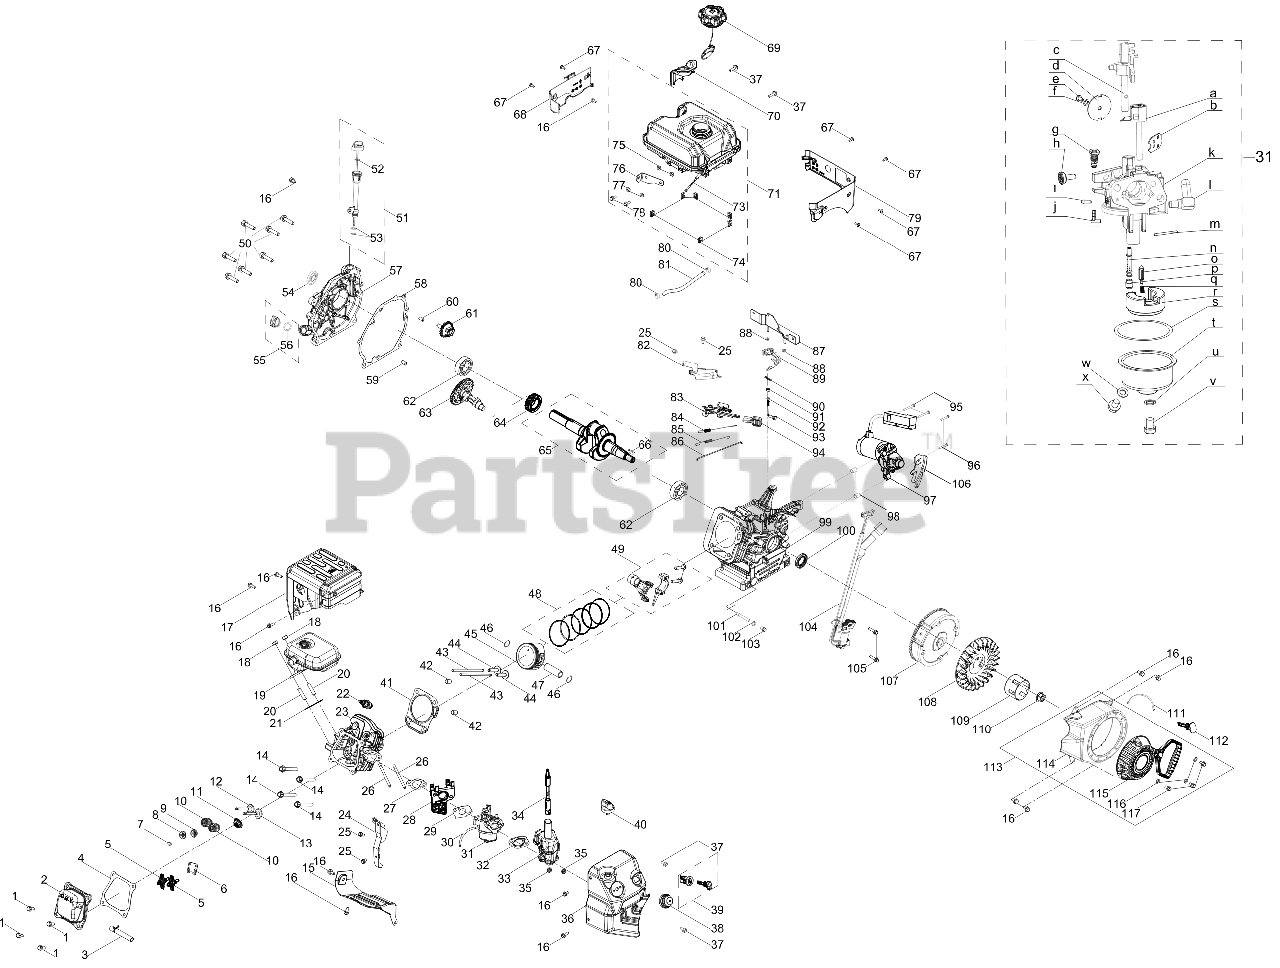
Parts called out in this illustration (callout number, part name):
1	BOLT M6 x 16
2	VALVE COVER
3	BREATHER HOSE
4	VALVE COVER GASKET
5	ROCKER ARM ASSEMBLY
6	ROCKER ARM BASE
7	EXHAUST VALVE ADJUSTER
8	EXHAUST VALVE SPRING RETAINER
9	INTAKE VALVE SPRING RETAINER
10	VALVE SPRING
11	INTAKE VALVE SEAL
12	EXHAUST VALVE
13	INTAKE VALVE
14	BOLT M8-1.25 x 55 GR10.9
15	AIR SHIELD
16	BOLT M6-1 x 12 GR8.8
17	MUFFLER GUARD
20	STUD M8 x 36
21	MUFFLER GASKET
22	SPARK PLUG
23	CYLINDER HEAD
24	SNOW GUARD
25	BOLT M6-1 x 12 GR8.8
26	STUD M6 x 90
27	CARBURETOR INSULATOR GASKET
28	CARBURETOR INSULATOR
29	CARBURETOR GASKET
30	PRIMER HOSE
31	CARBURETOR ASSEMBLY
32	CARBURETOR GASKET PLATE
33	HEATER BOX
34	CHOKE LEVER
36	CONTROL PANEL
37	BOLT M6-1 x 18 GR8.8
39	ENGINE KEY SWITCH ASSEMBLY
40	CHOKE LEVER
41	CYLINDER HEAD GASKET
43	PUSH ROD
46	PISTON PIN SNAP RING
47	PISTON PIN
48	PISTON RING SET
49	CONNECTING ROD ASSEMBLY
50	BOLT M8-1.25 x 32 GR5.8
51	DIPSTICK ASSEMBLY
52	DIPSTICK O-RING
53	OIL FILL TUBE O-RING
54	OIL SEAL
56	O-RING 15.8 x 2.5
57	CRANKCASE COVER
58	CRANKCASE COVER GASKET
59	DOWEL PIN
60	DOWEL PIN
61	GOVERNOR GEAR/SHAFT ASSEMBLY
64	DRIVE TIMING GEAR
65	CRANKSHAFT
66	FLYWHEEL KEY
67	BOLT: M5 x 14
68	FUEL TANK SHROUD (RH)
70	DECORATIVE COVER
73	FUEL FILTER
74	FUEL TANK MOUNT THREADED TAB
76	FUEL TANK MOUNT TAB
77	WASHER 6.5 x 1.5 x 12
78	BOLT M6 x 20
79	DECORATIVE SHEET (LH)
80	HOSE CLAMP
81	FUEL HOSE 6.3 x 12.5 x 162
82	GOVERNOR SHIELD
83	GOVERNOR GEAR BRACKET ASSEMBLY
84	GOVERNOR SPRING
85	THROTTLE RETURN SPRING
86	GOVERNOR ROD
87	FUEL TANK BRACKET
89	GOVERNOR LEVER
90	COTTER PIN
91	GOVERNOR SEAL
93	GOVERNOR SHAFT
94	THROTTLE CONTROL KNOB
96	BOLT M6-1 x 32 GR8.8
97	ELECTRIC STARTER
98	DOWEL PIN
100	OIL SEAL
101	OIL DRAIN PIPE
102	WASHER
103	OIL DRAIN PLUG
104	IGNITION MODULE
105	BOLT M6-1 x 25 GR8.8
106	LOWER SHIELD
107	FLYWHEEL
108	COOLING FAN
109	STARTER CUP
110	FLYWHEEL NUT
111	CABLE TIE - 3 x 150
112	IGNITION KEY
113	RECOIL STARTER
114	BLOWER HOUSING
115	RECOIL STARTER ASSEMBLY
116	RECOIL FLAT WASHER
117	BOLT M6 x 10
